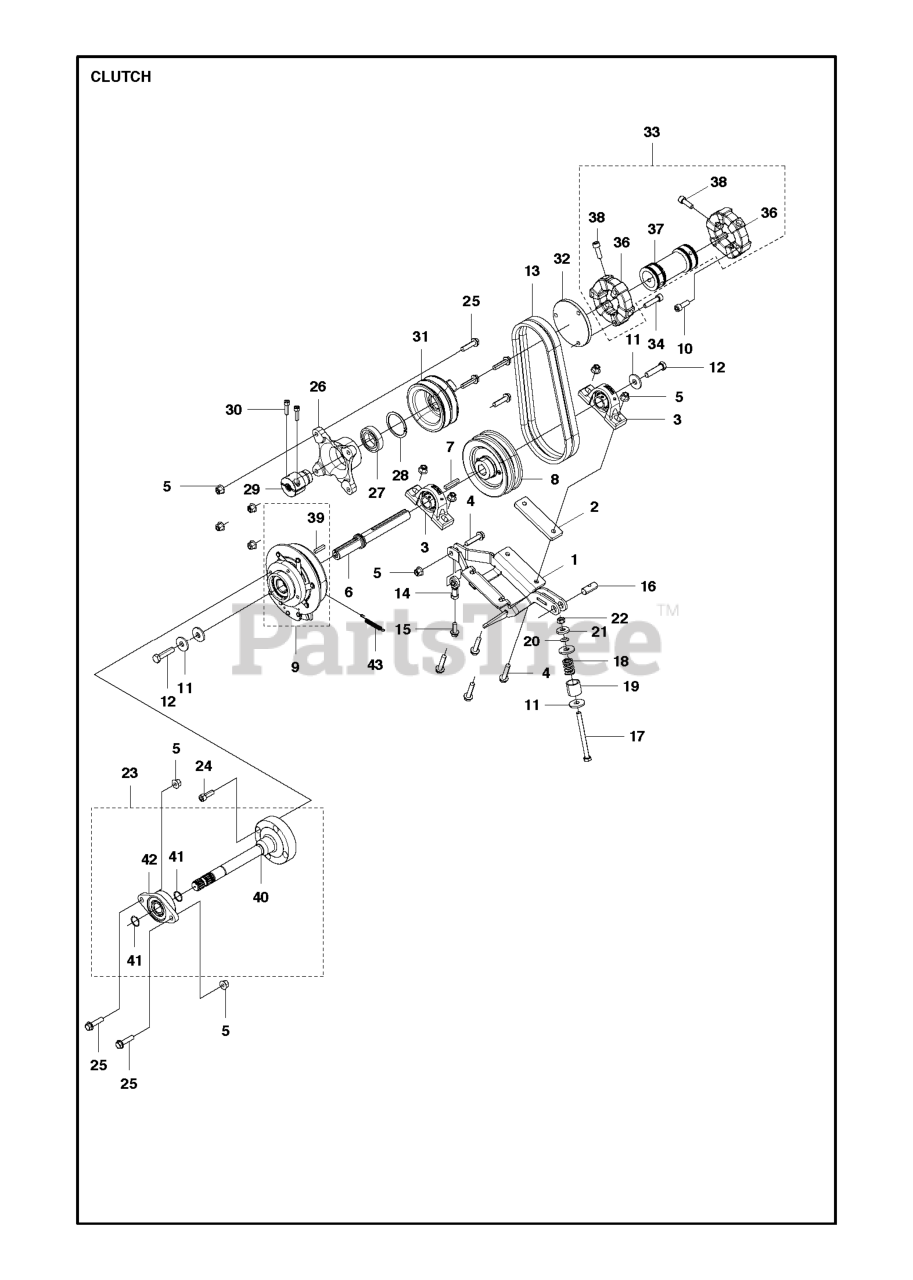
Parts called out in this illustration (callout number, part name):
4	COLLAR SCREW
22	NUT
24	SCREW IHSCM M10X30 12.9 ZPB L
34	SCREW IHSCM M10X45 12.9 ZPB L
42	BEARING UNIT FYTB 25TF
